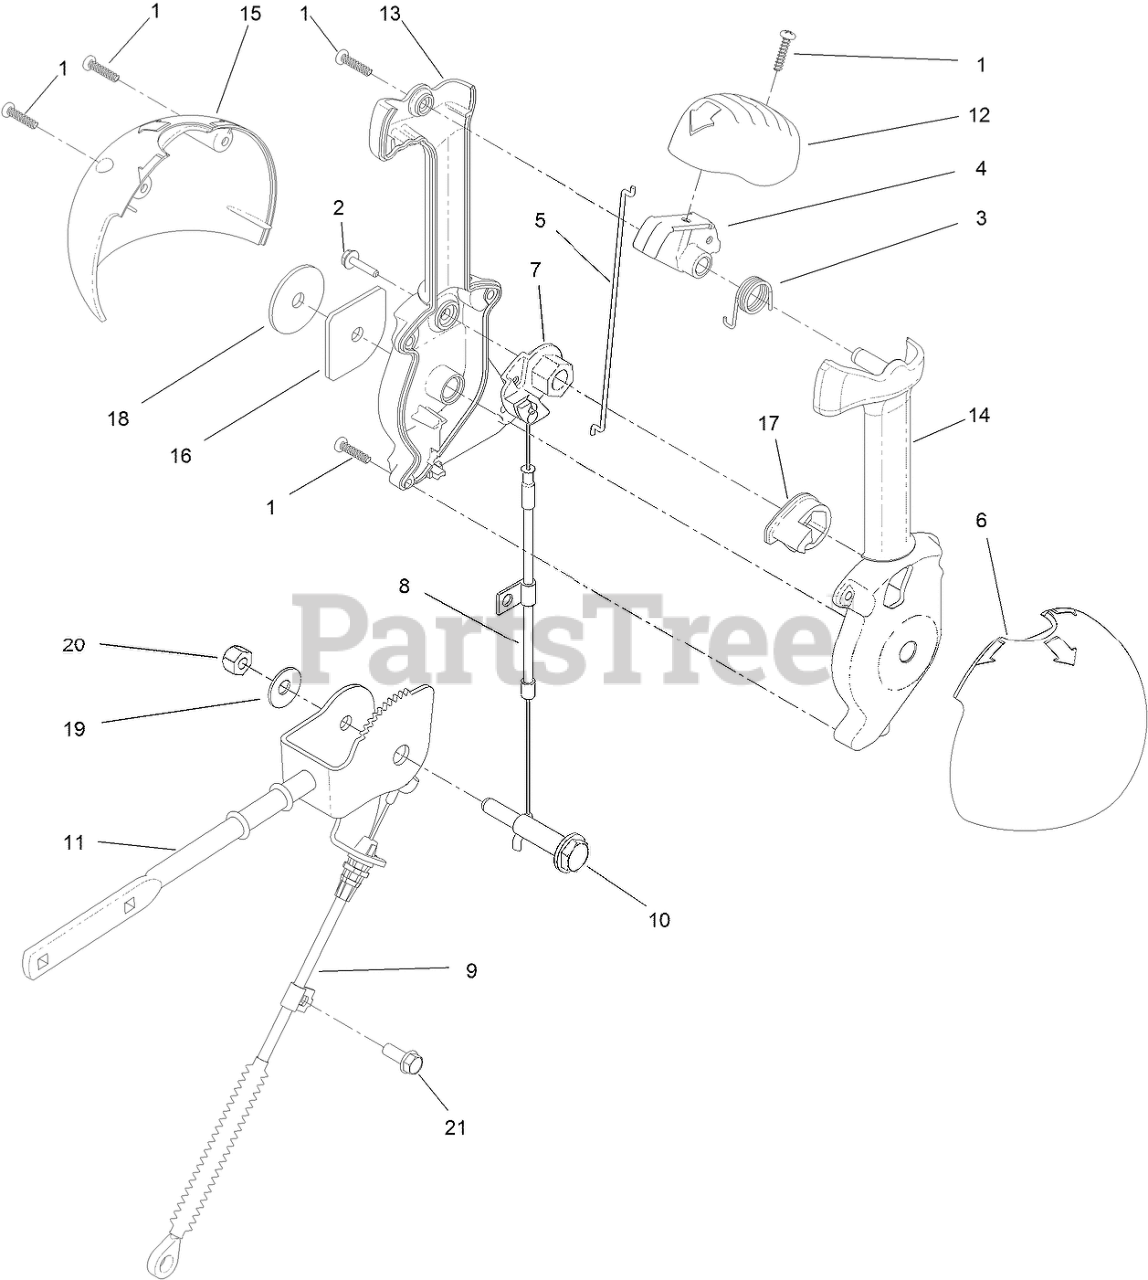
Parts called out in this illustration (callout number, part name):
1	SCREW-PPH
2	SCREW-PLASTITE, HWH
3	SPRING-TORSION
4	TRIGGER-LATCH
5	LINK-LATCH
6	COVER-LEVER, CHUTE (LH)
7	LEVER-CABLE, DEFLECTOR
8	CABLE-RELEASE, CHUTE
9	CABLE-CONTROL, DEFLECTOR
10	SCREW-SHOULDER
11	CHUTE CONTROL ROD
12	CAP-LEVER
13	LEVER-CONTROL, CHUTE (RH)
14	LEVER-CONTROL, CHUTE (LH)
15	COVER-LEVER, CHUTE (RH)
16	PLATE-FRICTION
17	PAWL-LATCH
18	WASHER-NYLON
19	WASHER-BELLEVILLE
20	NUT-HEX
21	SCREW-HWH
